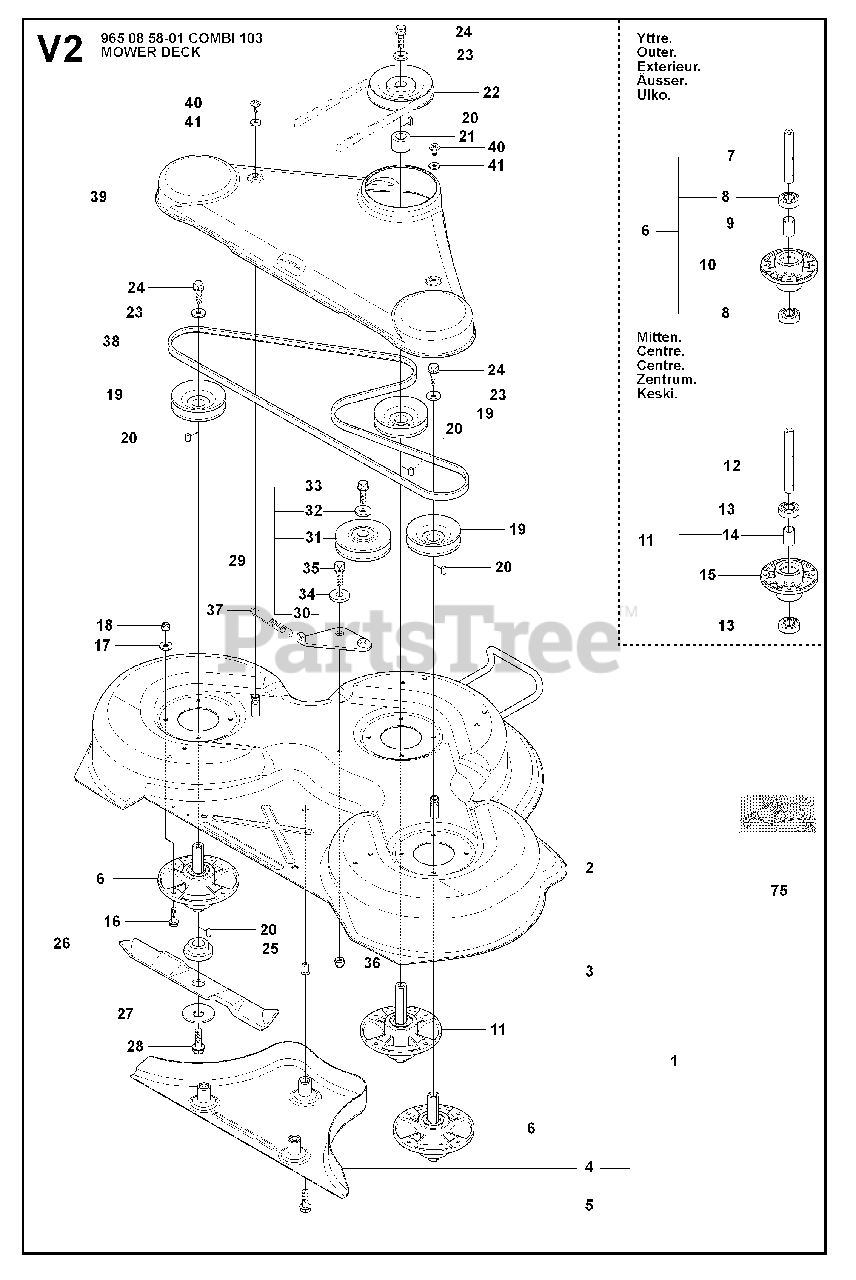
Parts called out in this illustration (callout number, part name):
6	RP SPINDLE ASSY
10	BEARING HOUSING
11	RP SPINDLE ASSY
15	BEARING HOUSING
17	WASHER BRB 8.4X17
18	LOCKNUT M8
26	BLADE
29	BELT TENSIONER ASSY
30	BELT TENSIONING ARM
34	WASHER
36	LOCKNUT M8
38	BELT
44	LOCKNUT M8
51	LOCKNUT M8
52	PARALLEL RODY ASSY
58	CLUTCH ROD ASSY
67	LOCKNUT M8
68	DECK ROLLER, FRONT
70	RETAINING RING SGA 15
73	WASHER
74	LOCKNUT M6
